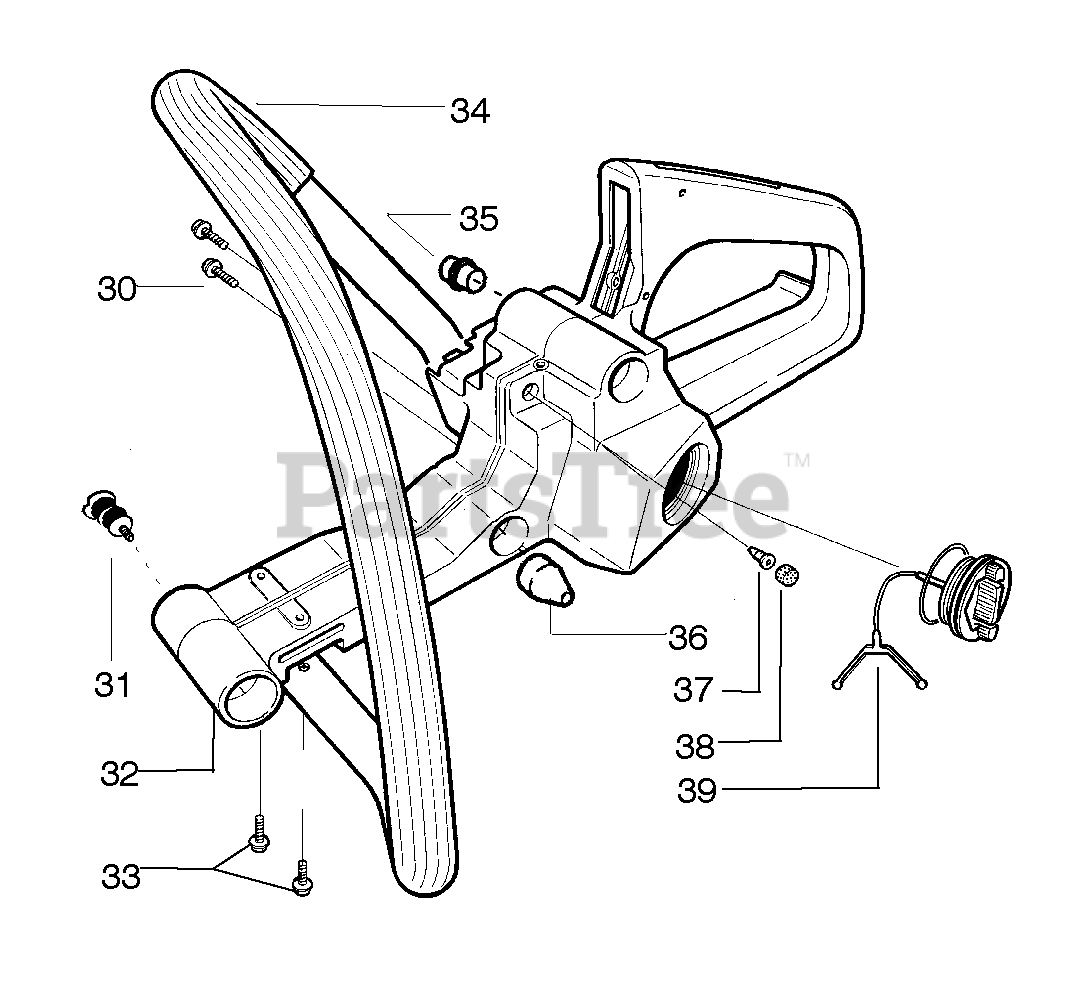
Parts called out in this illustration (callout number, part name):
31	Element - AV Isolator
32	Assy. -Tank/Handle
34	Handle-Front
35	Isolator-Front Handle
37	Valve - Check
38	Plug - Vent
39	Kit-Assy. Fuel Cap
